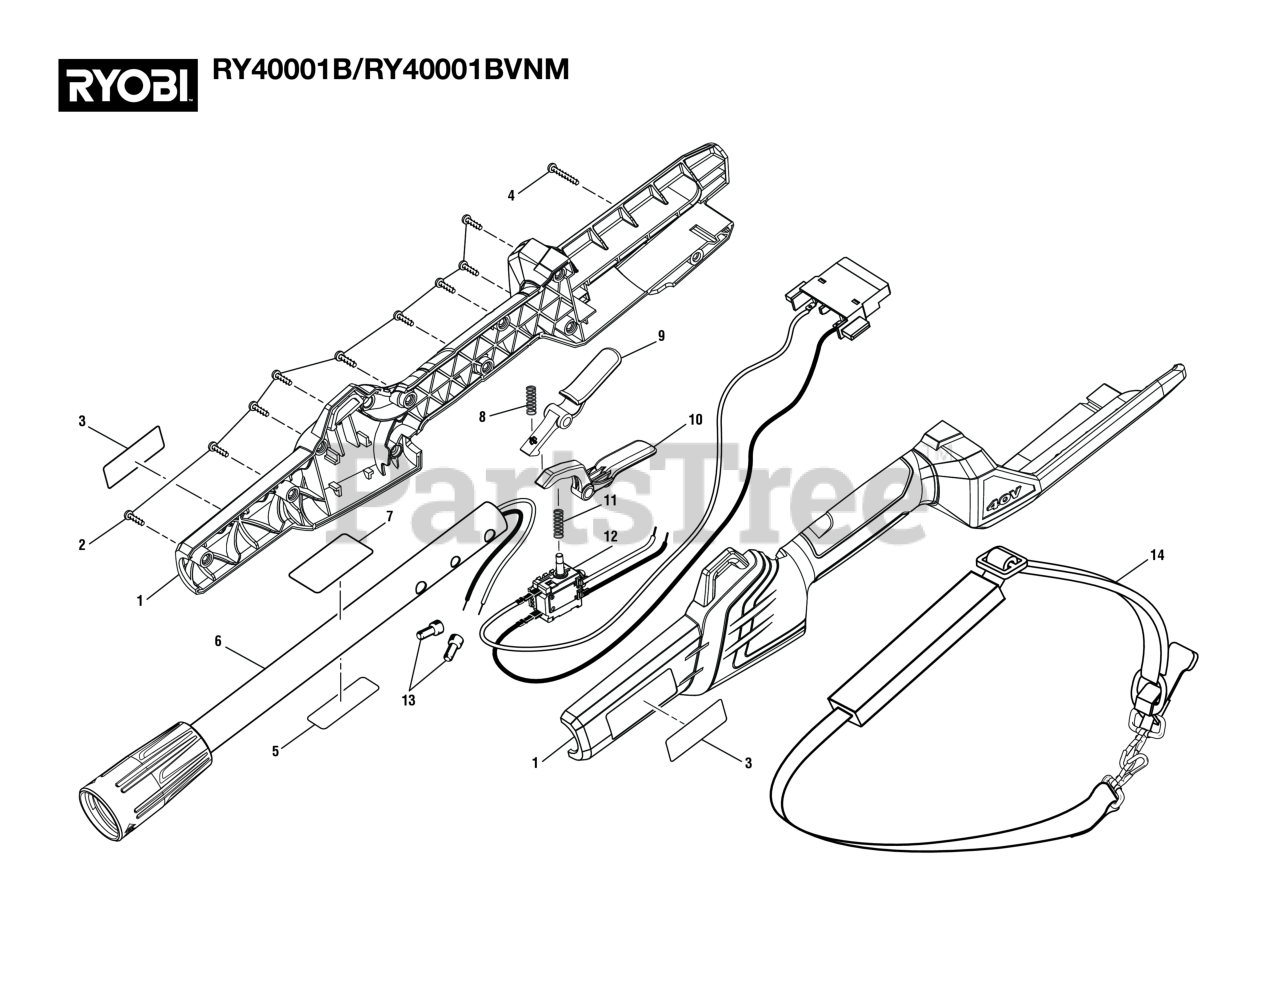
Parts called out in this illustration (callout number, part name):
1	Rear Handle Assembly (Inc. Key No. 3)
2	Screw (M4 x 14 mm, T15 Torx Pan Hd.))
3	Logo Label
4	Screw (M4-18 x 30 mm, T15 Torx Soc. Hd.)
5	Data Label
6	Upper Tube Assembly
7	Warning Icon Label
8	Compression Spring (Trigger)
9	Lock Off Button (Trigger Lock)
10	Switch Trigger
11	Compression Spring (Trigger)
12	Switch and Contact Plate Assembly
13	Wire Connector (Closed End)
